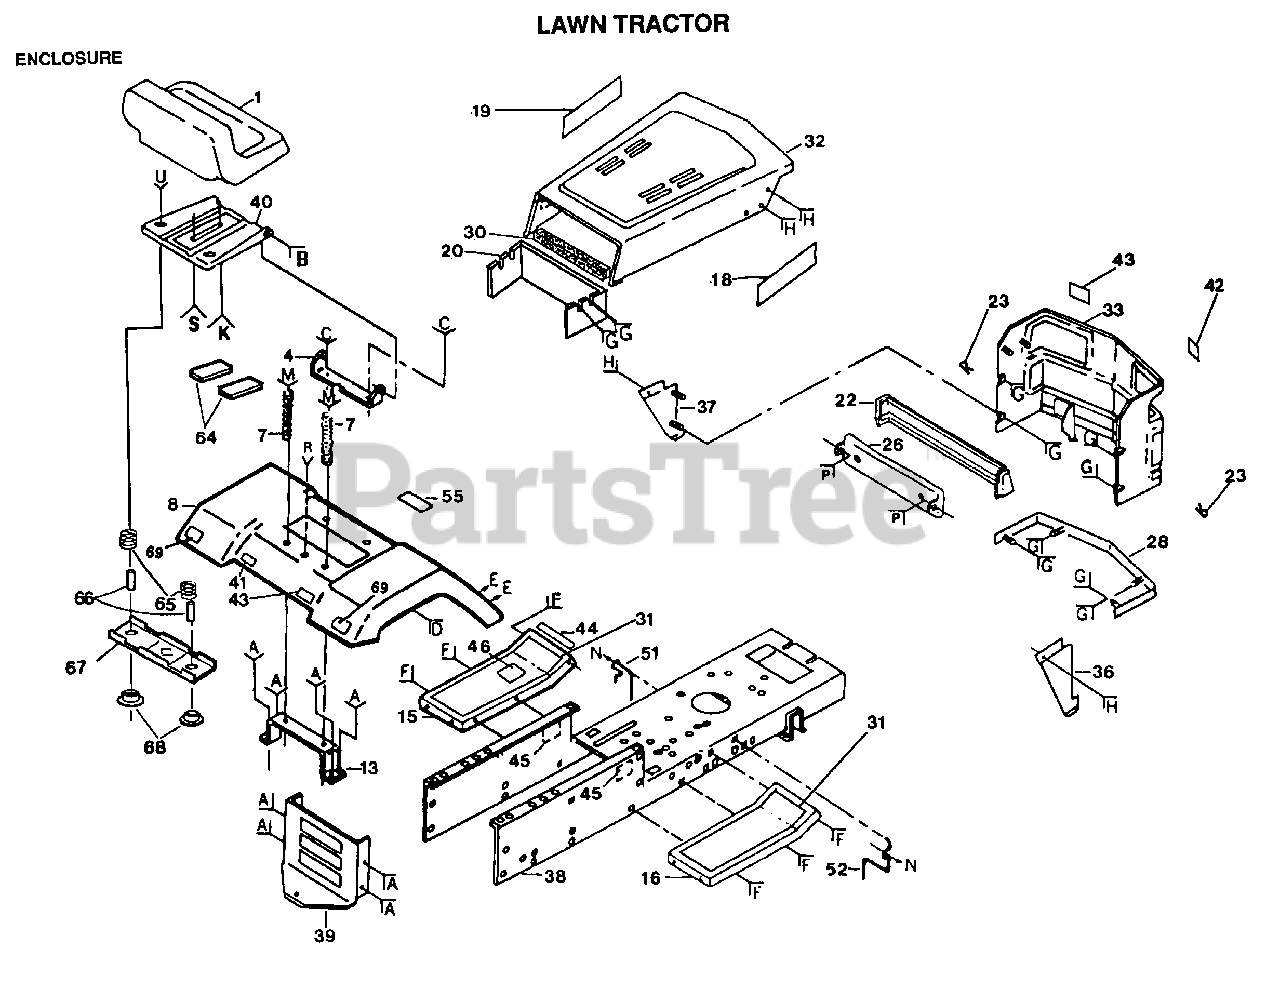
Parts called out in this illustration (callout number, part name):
7	SPRING COMPRESSIO
18	DECAL, HOOD R.H.
19	DECAL, HOOD L.H.
20	"SHIELD,HEAT"
23	SPRING.RETAINER
30	FOAM-STRIP LT
31	PAD FOOTREST T
38	CHASSIS ASS'Y
41	"DECAL,FENDER T"
42	"DECAL,GRILL"
43	"DECAL,GRILL HP T"
44	DECAL T
45	DECAL, CHASSIS, SPEED/DECK SIZE
51	BELT GUIDE
52	BELT GUIDE
64	STRIP FORM
65	SPRING
66	SPACER SPLIT
67	BRKT SWITCH
68	BUSHING
69	REFLECTOR-TAIL YT
